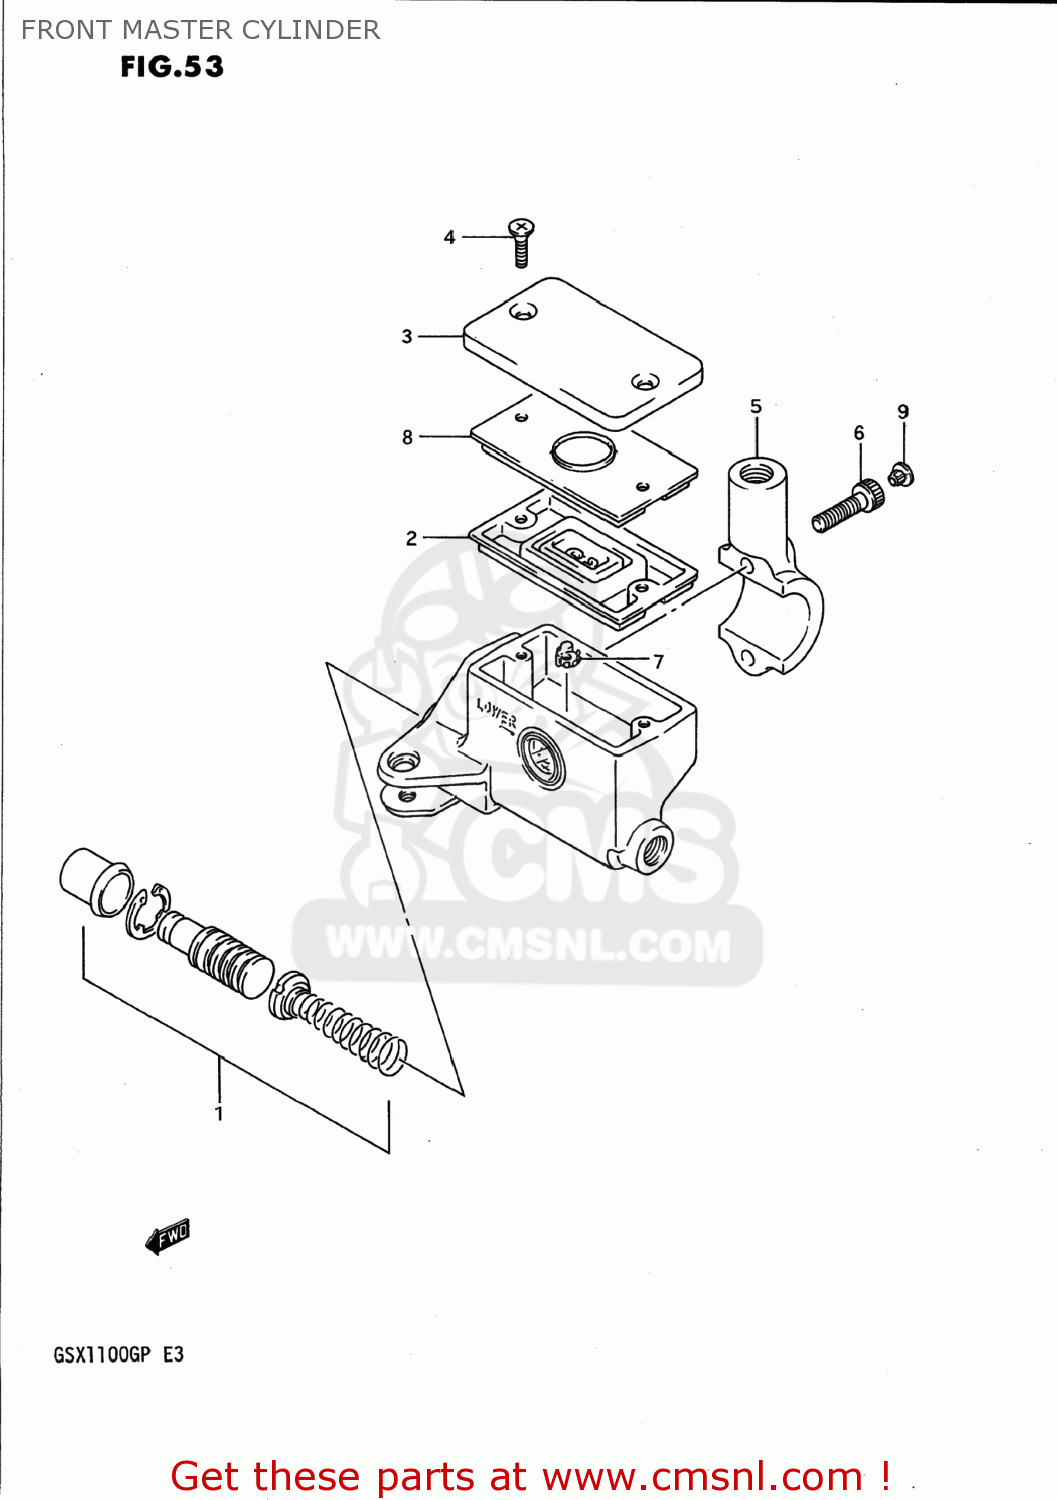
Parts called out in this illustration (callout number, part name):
1	PISTON & CUP SET
2	3
3	CAP
4	SCREW,RESERVOIR CAP
5	HOLDER
6	BOLT ,6X20
7	PROTECTOR
8	PLATE,DIAPHRAGM
9	CAP(OD:10)
